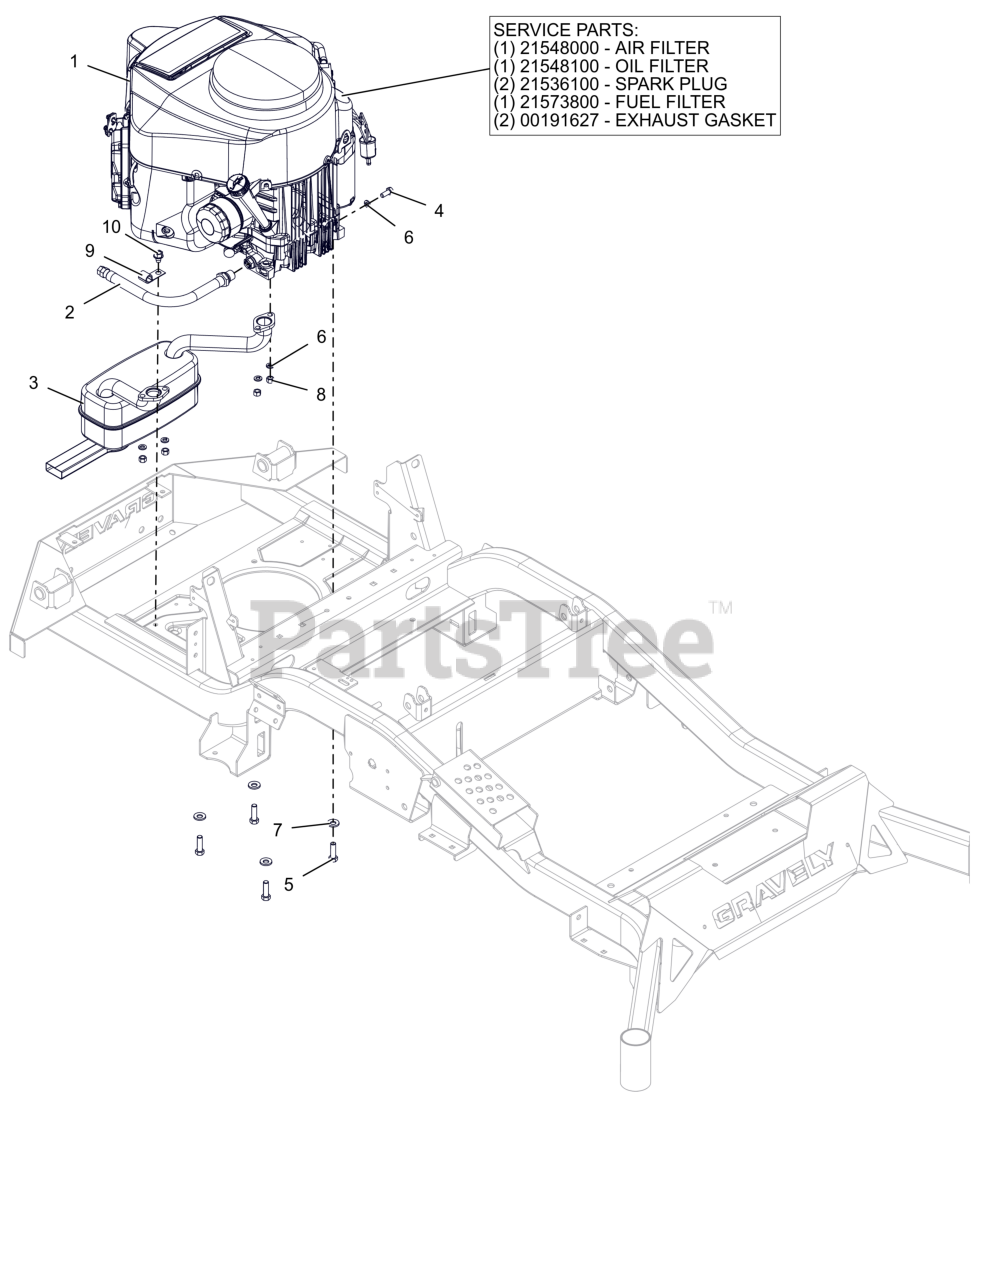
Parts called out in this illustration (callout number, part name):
1	ENGINE, KAWASAKI FR730 24HP
1	AIR FILTER, KAWASAKI FR
1	OIL FILTER, KAWASAKI FR
1	PLUG, SPARK
1	FUEL FILTER
1	GASKET, MUFFLER S/O
2	HOSE, OIL DRAIN
3	MUFFLER, KAWASAKI
4	BLT, HEX M8-1.25X20 G8.8 ZCC
5	BLT, HEX .38-16X1.25 G5 ZCC NT
6	WSHR,LK-REG .312X.078 ZCC
7	WASHER, 3/8" SPRING DISC
8	NUT-LK-TOP-FLG M8 ZCC
10	SCR,TAP .375-16X.50 HWH TR ZCC
